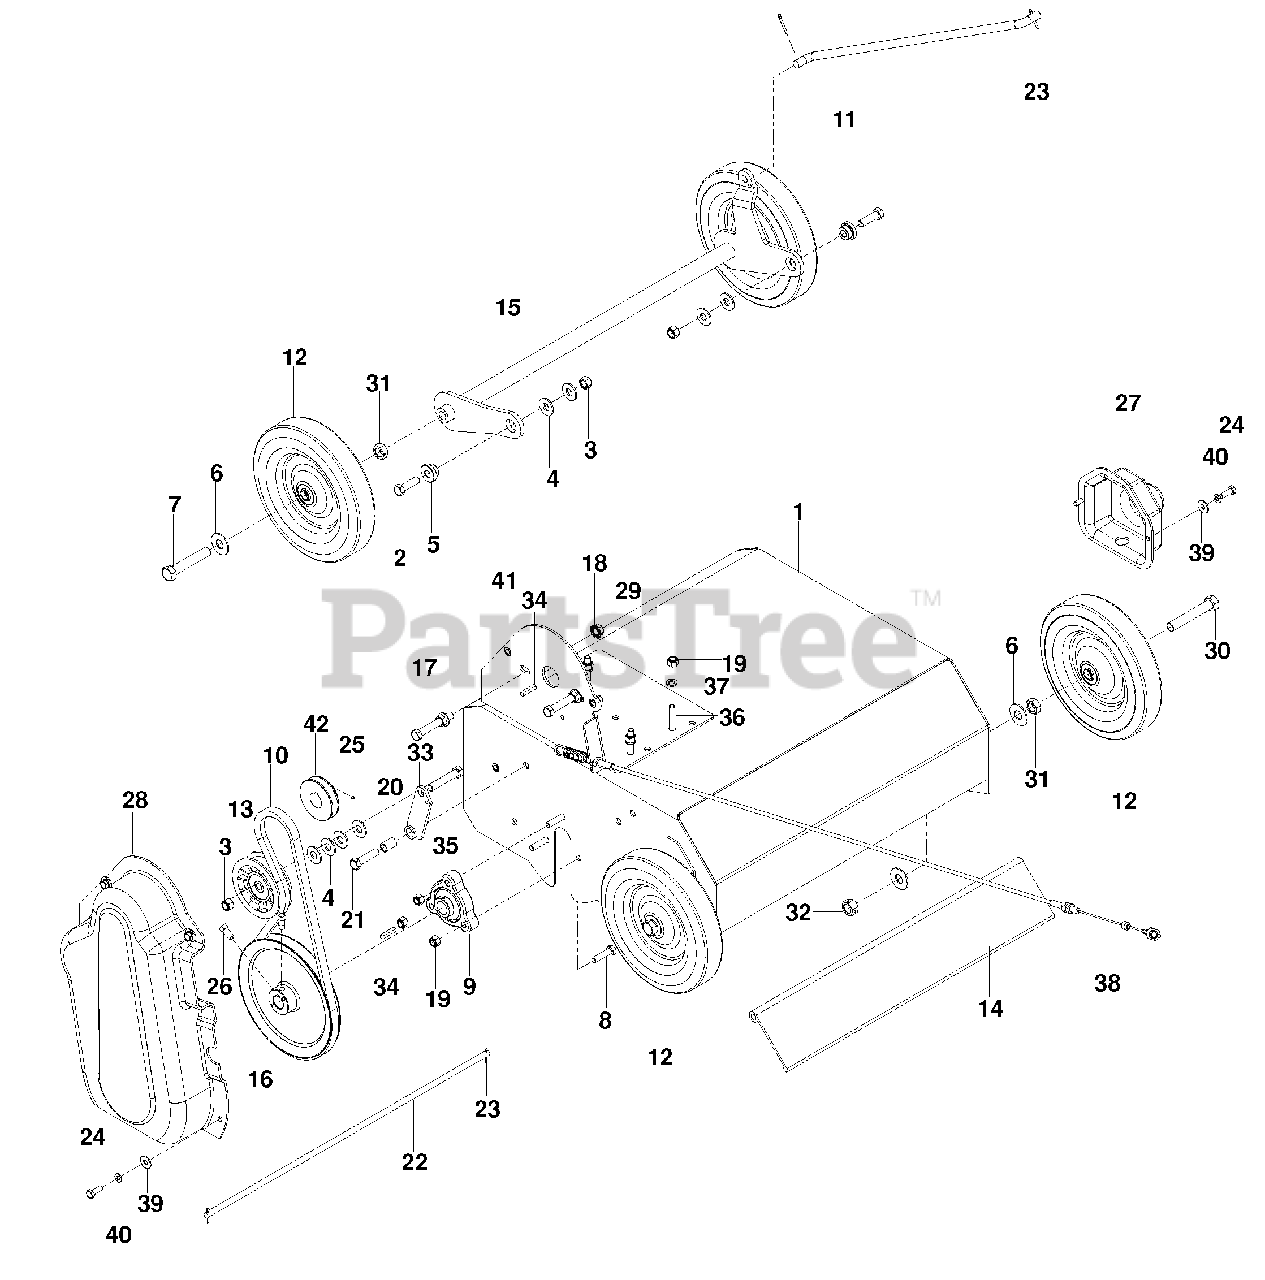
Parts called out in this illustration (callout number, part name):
1	BODY W/DECALS
2	HCS 3/8-16 x 1 1/4
3	NUT 3/8-16 NYLOC
4	WASHER 3/8 FLAT
6	WASHER 1/2 FLAT
7	HCS 1/2 -13 x 2 3/4
8	HCS 5/16-18 x 1 1/4
9	BEARING, FLANGE
12	WHEEL 8 x 1 3/4
13	PULLEY, IDLER
15	FRONT AXLE
17	HCS 3/8-16 x 2 1/2
18	NUT 3/8-16 SERRATED
19	NUT 5/16-18 NYLOC
21	HCS 3/8-16 x 1 1/2
23	COTTER PIN
24	HCS 1/4-20 x 3/4
25	KPSS 5/16-18 x 3/8
26	SCREW-18 x 5/8 SET
27	GUARD, SHAFT
28	GUARD, BELT
29	BACKING PLATE
30	HCS 1/2-13 x 3
31	NUT 1/2-13 JAM
32	NUT 1/2-13 CNTRLK
34	KEY 3/16 x 3/16 x 1
35	HCS 3/8-16 x 2
36	HCS 5/16-18 x 1 3/4
37	LOCKWASHER 5/16
39	WASHER 1/4
40	LOCKWASHER 1/4
41	KNURLED INSERT 1/4-20
42	PULLEY
